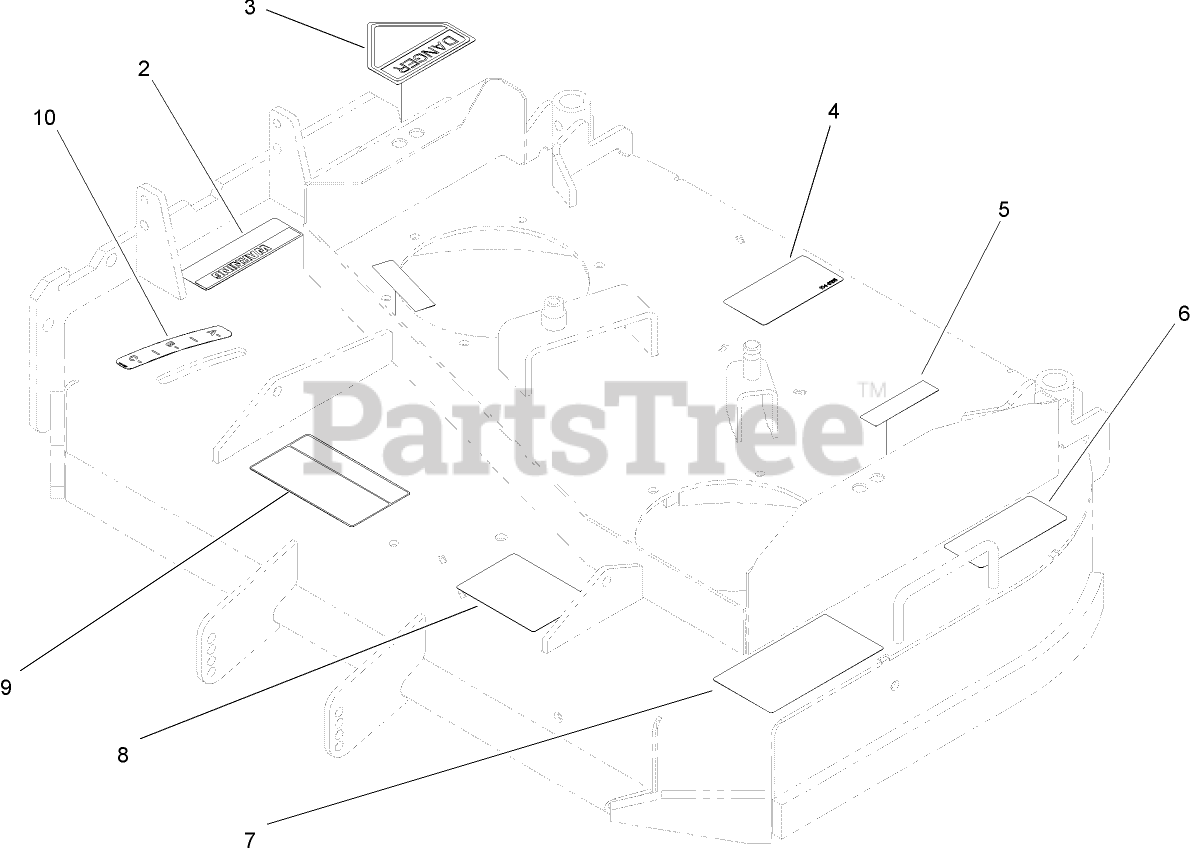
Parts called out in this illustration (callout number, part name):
2	DECAL-WARNING
3	DECAL-DANGER
5	DECAL-COVER, MISSING
6	DECAL-TORQUE
7	DECAL-DANGER, THROWN OBJECT
8	DECAL-SCALP, ANTI
9	DECAL-ADJUSTMENT, BAFFLE
10	DECAL-SETTING, BAFFLE
